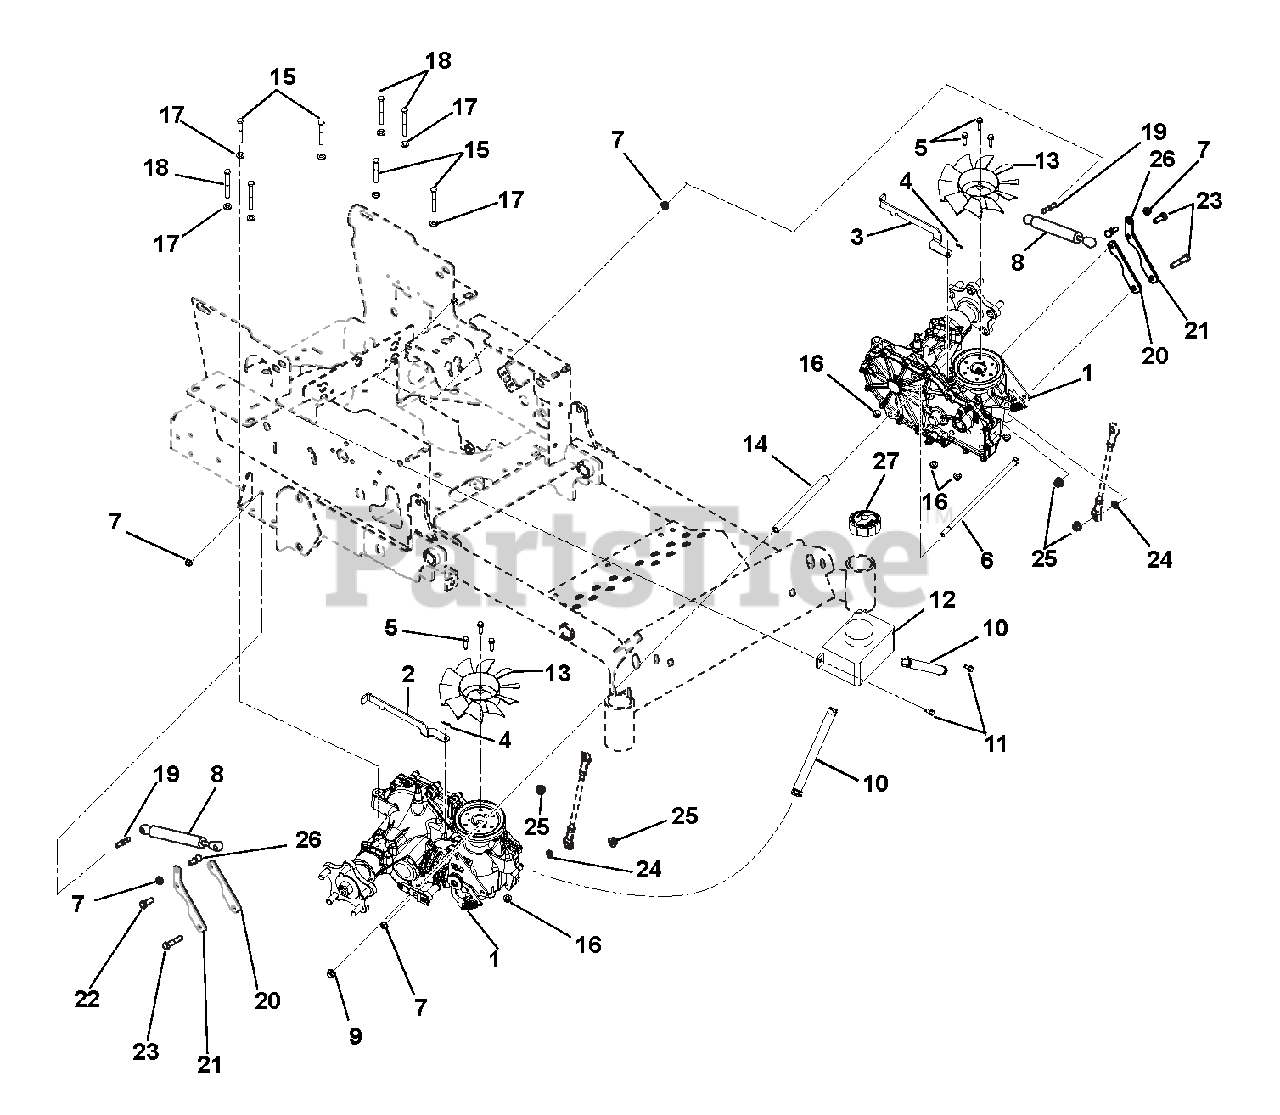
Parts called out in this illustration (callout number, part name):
1	TRANSAXLE, 3100 SERIES - LH
2	RH DUMP VALVE LEVER - BLACK
3	LH DUMP VALVE LEVER - BLACK
4	PIN-HAIR INT .06X.18X.77
5	@SCR-TAP .25-20X1.00 HWH TR YZ
6	BLT HEX, .38-16X11.00 GR5 YWZC
7	@NUT-LK-TOP-FLG .31-18 YWZC
8	DAMPER, STABILUS
9	@NUT-LK-NYL-FLG .38-16 YWZC
10	ASM, HYDRO OVERFLOW TANK HOSE
11	@SCR-TAP .25-20X.50 HWH TR YWZ
12	TANK, EXPANSION
13	FAN, 2800 SERIES COOLING
14	SPCR,.406 ID X .630 OD X 7.724
15	@BLT-HEX .31-18X2.50 GR5 YWZC
16	@NUT-LK-NYL-FLG .31-18 YWZC
17	@WSHR-FL-STL.344X.688X.065YWZC
18	@BLT-HEX .31-18X3.00 GR5 YWZC
19	STUD-BALL-THREADED
20	PLATE, CONTROL REINFORCEMENT
21	PLATE,TRANSMISSION DAMPER MTG
22	@BLT-HEX .38-16X1.00 GR5 YWZC
23	@BLT-HEX .38-16X1.75 GR5 YWZC
24	@WSHR-LK .38X.094 REG YWZC
25	@NUT-LK-NYL-FLG .38-16 YWZC
26	STUD- BALL
27	CAP, HYDRO RESERVOIR REPLAC.
